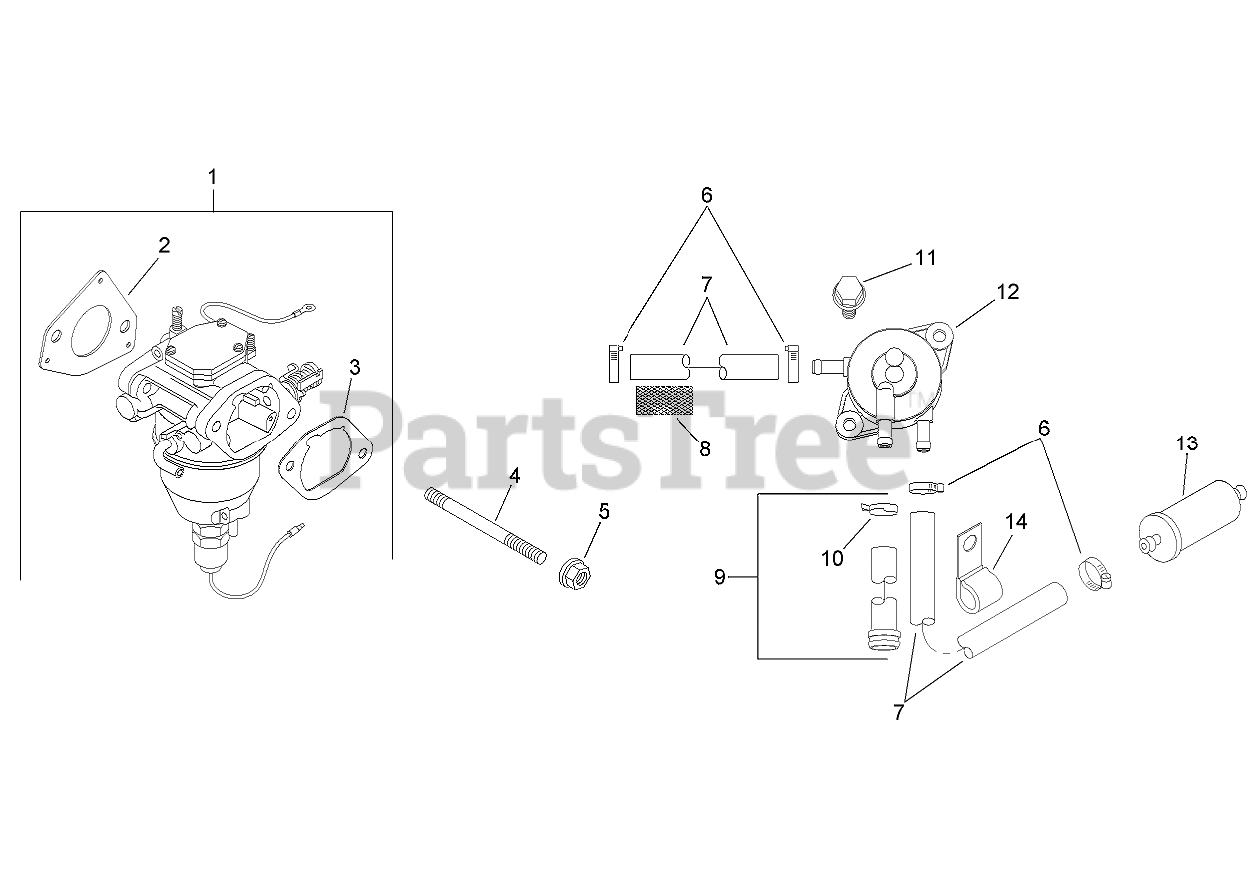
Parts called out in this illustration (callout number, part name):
1	CARBURETOR KIT W/GASKETS
2	GASKET-CARBURETOR
3	GASKET-BASE, AIR CLEANER
4	STUD (M6X1.0X106)
5	NUT-FLANGE (M6X1.0)
6	CLAMP-HOSE, SPRING (1/2)
7	LINE-FUEL (24.0 CUT TO LENGTH)
8	SLEEVE-ABRASION, ANTI
9	FUEL PUMP HOSE KIT (W/CLAMP)
10	CLAMP-HOSE
11	SCREW-TAP (M6X1.7X18)
12	PUMP-FUEL
13	FILTER-FUEL
14	CLIP-CABLE
